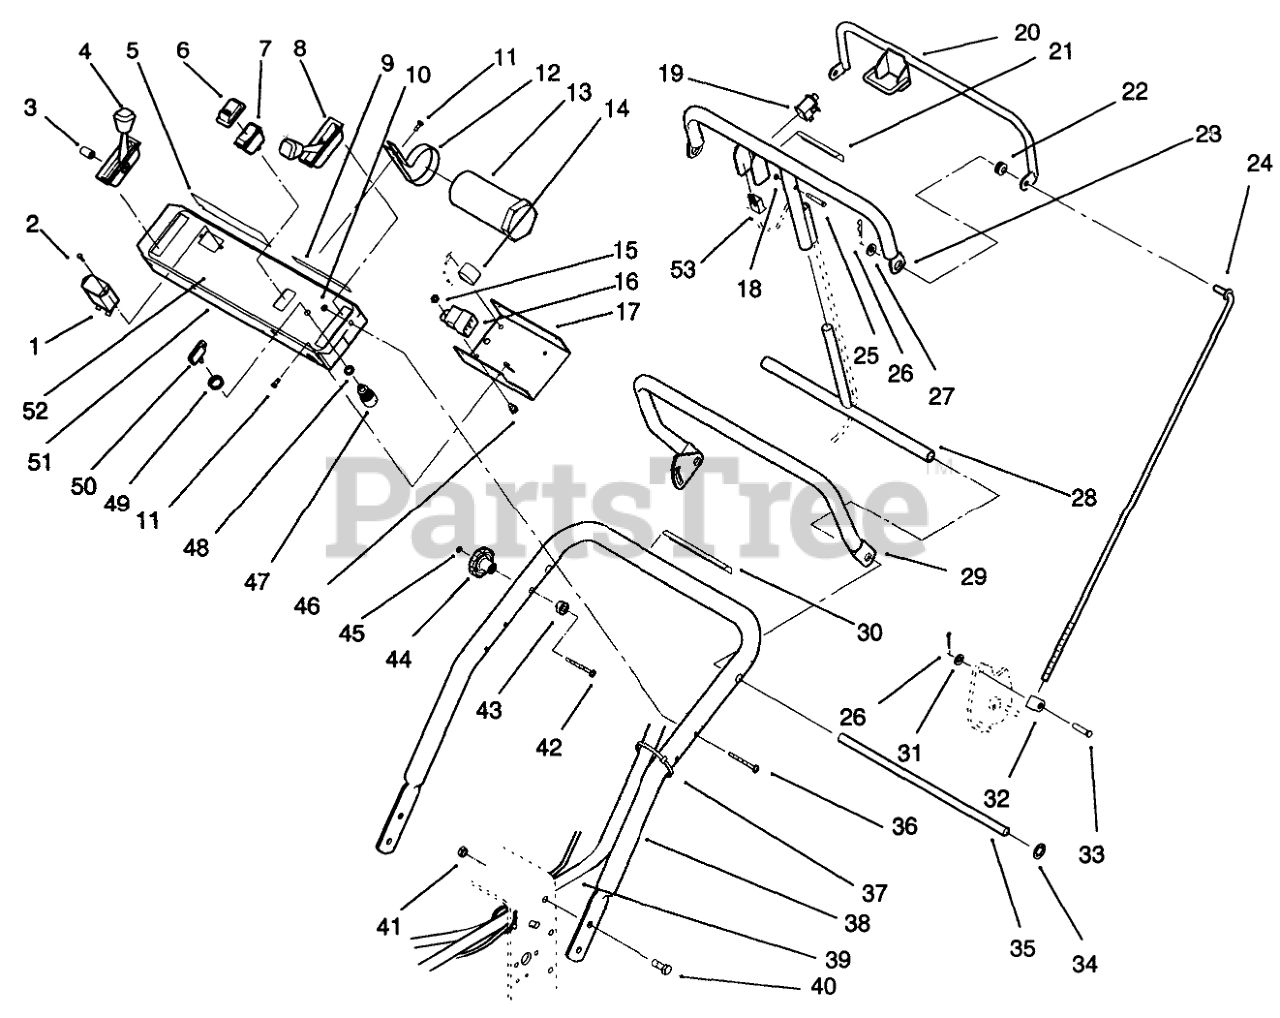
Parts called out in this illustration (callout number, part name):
1	HOURMETER
2	SCREW-HWH
3	SPACER
4	CHOKE CONTROL
5	DECAL-INSTRUCTION, SAFETY
6	BOOT-SWITCH
7	SWITCH
8	THROTTLE CONTROL
9	DECAL-INSTRUCTION
10	NUT-LOCK, NI
11	SCREW-HWHTF
12	CLAMP-R
13	TUBE-MANUAL
14	Module
15	NUT-LOCK, NI
16	RELAY
17	Panel-Bottom
18	NUT-LOCK, NI
19	SWITCH-BAIL
20	Bail
21	DECAL - CONTROL BAR
22	GROMMET-RUBBER
23	Bar
24	ROD-CONTROL
25	SCREW-SHH
26	PIN-COTTER
27	WASHER-FLAT
28	Pivot Control Assembly
29	REFERENCE HANDLE WA B
30	DECAL-WARNING
31	WASHER-PLAIN
32	FITTING-ROD
33	PIN-CLEVIS
34	NUT-PUSH-ON, CIRCULAR
35	PIVOT ROD
36	SCREW-SHH
37	TIE-CABLE
38	UPPER HANDLE R
39	WIRE HARNESS
40	SCREW-HHF
41	NUT-HF
42	Bolt Carriage
43	SPACER
45	BOLT RETAINER
46	SCREW-HH
47	SWITCH-STARTER
48	SCREW-HHF
49	NUT-HH
50	KEY-IGNITION
51	DECAL - CONTROL PANEL
52	Panel-Control
53	CONNECTOR-BODY
